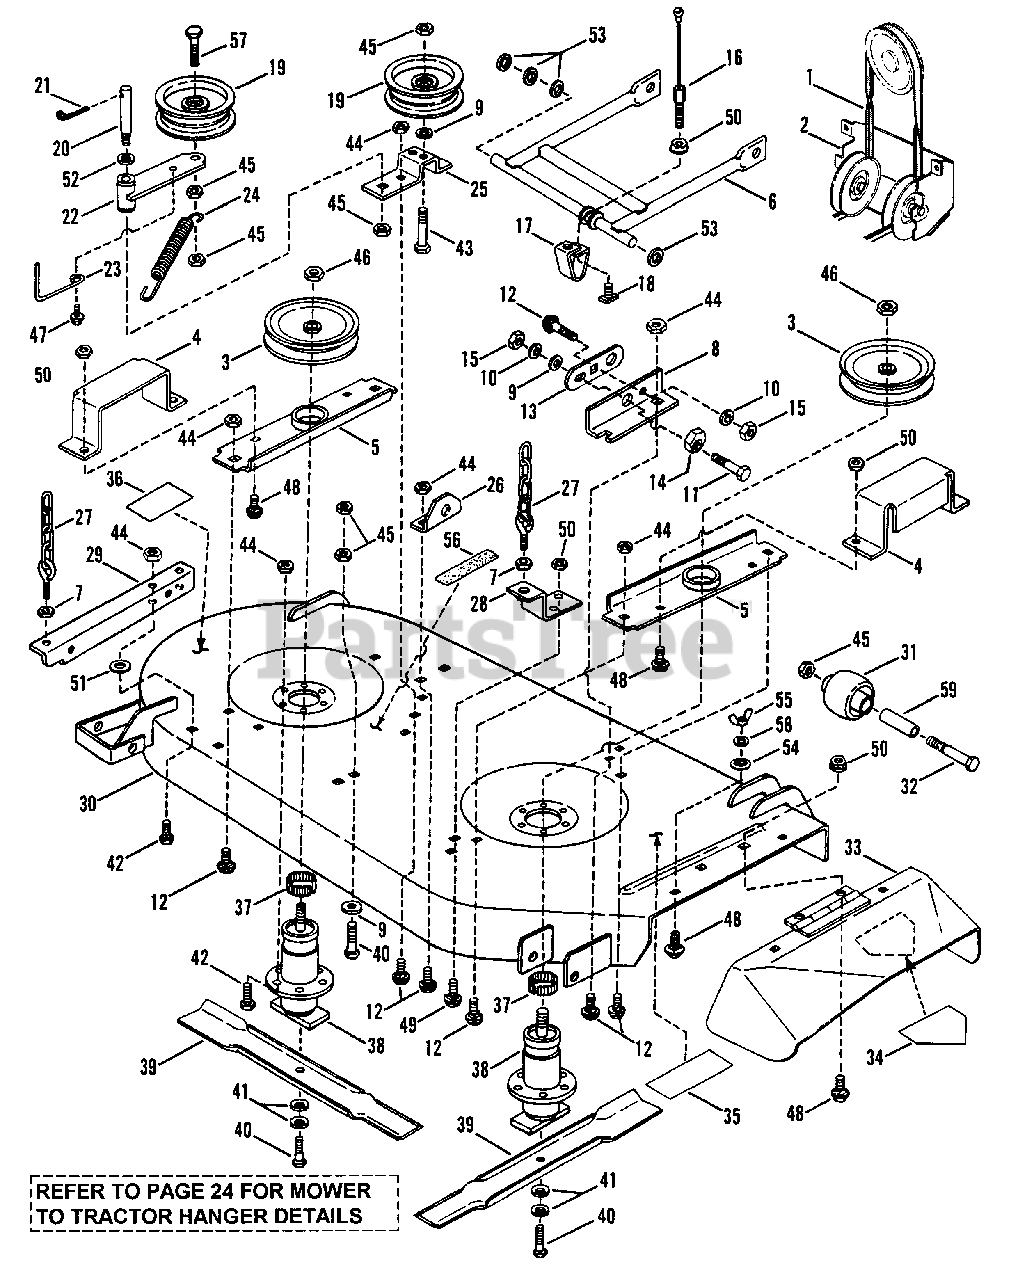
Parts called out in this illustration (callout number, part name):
1	BELT, 41" Mower (A137)
2	ASSEMBLY, Mule Drive
3	PULLEY, 5-3/4" O.D.
4	GUARD, Pulley
5	BRACE, Spindle
6	WELDMENT, Front Lift Arm
7	JAM-NUT, 3/8-16 Hex
8	BRACKET, Right Front
9	WASHER, 3/8" Flat
10	WASHER, 3/8 Split Lock
11	SCREW, 3/8-16 x 1" Hex Head
12	BOLT, 3/8-16 x 3/4" Square Neck Carriage, Grade 5
13	LINK, Adjustment
14	RING, Adjustment
15	NUT, 3/8-16 Hex
16	CABLE, Front Lift
17	BRACKET, Fr. Lift Arm Hanger
18	T-NUT, 5/16-18
19	PULLEY, 4.1 O.D.
20	STUD, Idler (3/8-24)
21	COTTER-PIN, 1/8 x 1"
22	ASY, Idler Arm
23	GUIDE, Belt
24	SPRING, Idler Arm
25	BRACKET, Idler
26	BRACKET, Front Left Hanger
27	ASY, 3/8 Bolt/Chain
28	BRKT, Rear Rt. Supp. (1985)
29	BRKT, Rear Left Supp. (1985)
30	MOWER DECK, 41"
31	WHEEL, Gage
32	SCREW, 3/8-24 x 3-3/4" Hex Head Cap, Grade 5
33	DEFLECTOR, (Side Chute)
34	DECAL, Danger
35	DECAL, Caution (Deflector)
36	DECAL, Caution (Rot. Blades)
37	RING, Tolerance, 3/4"
38	ASY, Spindle
39	BLADE, 21" Cutter
40	SCREW, 3/8-24 x 1-1/4" Hex Head Cap, Grade 5
41	CONE-WASHER
42	BOLT, 3/8-16 x 3/4" HFL
43	SCREW, 3/8-24 x 1-3/4" Hex Head cap, Grade 5
44	NUT, 3/8-16 Hex Fl. Lock
45	NUT, 3/8-24 Hex Ctr. Lk.
46	NUT, 3/4-16 Jam Lock
47	SCREW, 1/4-20 x 5/8" HWST
48	BOLT, 5/16-18 x 5/8" Square Neck Carriage, Grade 5
49	BOLT, 5/16-18 x 1/2" Hex Flange Lock, Grade 5
50	NUT, 5/16-18 Hex Flange Lock, Grade 5
51	WASHER, 3/8" Flat
52	WASHER, 5/8 Flat
53	WASHER, Spacer
54	RETAINER, 5/16 Bolt
55	WING-NUT, 5/16-18
57	SCREW, 3/8-24 x 2" Hex Head Cap, Grade 5
58	WASHER, 5/16 Split Lock
59	SPACER
